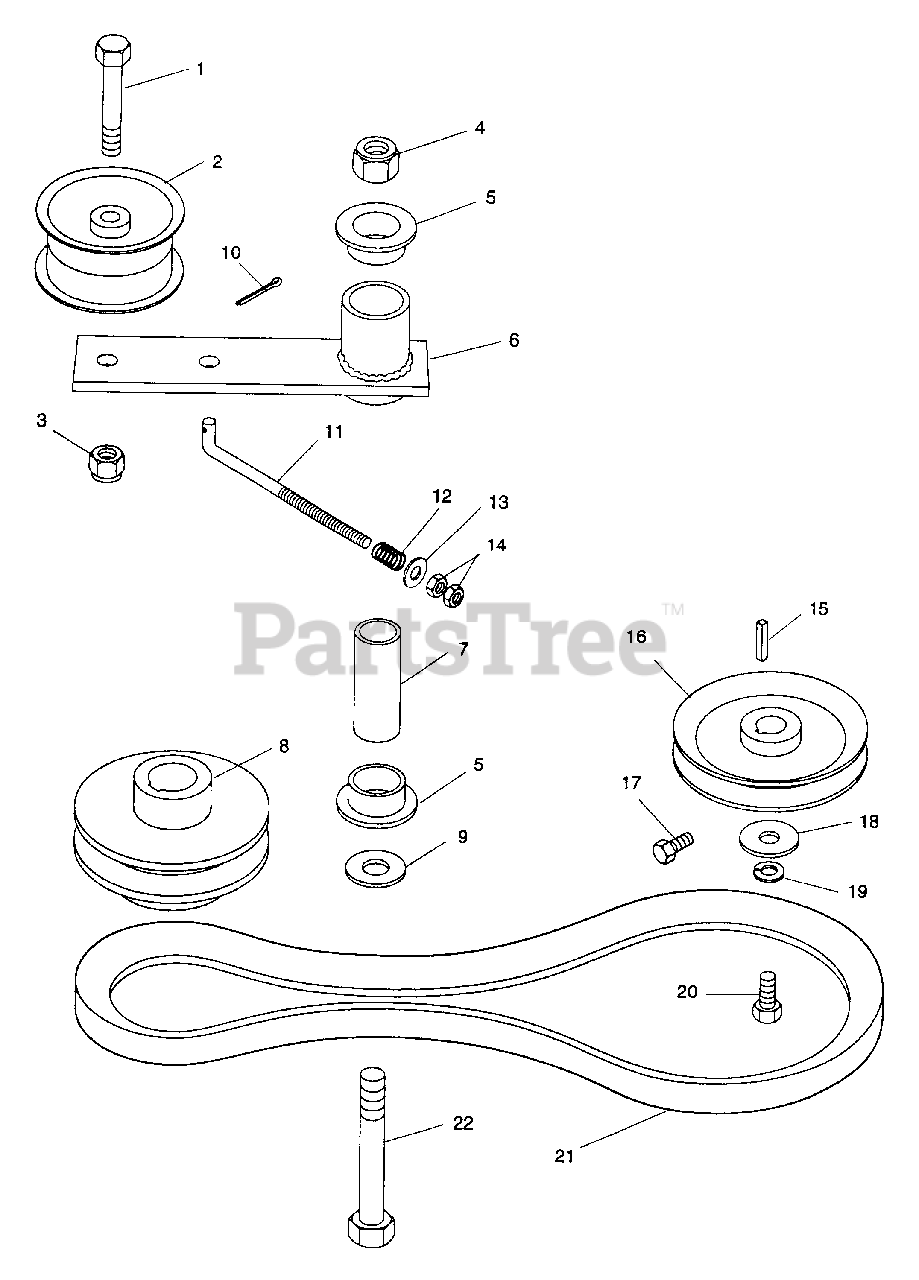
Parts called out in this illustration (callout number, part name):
1	Bolt, Hex .38-16 x 1.75 GR. 5
2	Idler, Pulley
3	Nut, Lock Nylon .375-16
4	Nut, Lock Nylon .50-13
5	Bushing, Flange .762 x 1.0 x .580 x 1.48 Nylon
6	Weldment, Ground Drive Idler
7	Bushing, 5.560 x .745 x 2.04 Steel
8	Sheave, Engine Ground Drive
9	Washer, Flange Steel .531 x 1.062 x .095
10	Pin, Cotter .09 x .75
11	Rod, Idler
12	Spring, compression .188 x 1.66 x 2.0
13	Washer, Flat Steel .406 x .812 x .065
14	Nut, Hex .375 x 24
15	Key, 5mm x 25mm x 5mm
16	Sheave, Hydralic Pump
17	Bolt, Hex .25-20 x .50 Gr. 5
18	Washer, Flat Steel .281 x 1.250 x .062
19	Washer, Lock .250 Reg.
20	Bolt, Hex M6 x 1.0 x 12mm
21	V-Belt Engine to Pump
22	Bolt, Hex .50-13 x 3.00
